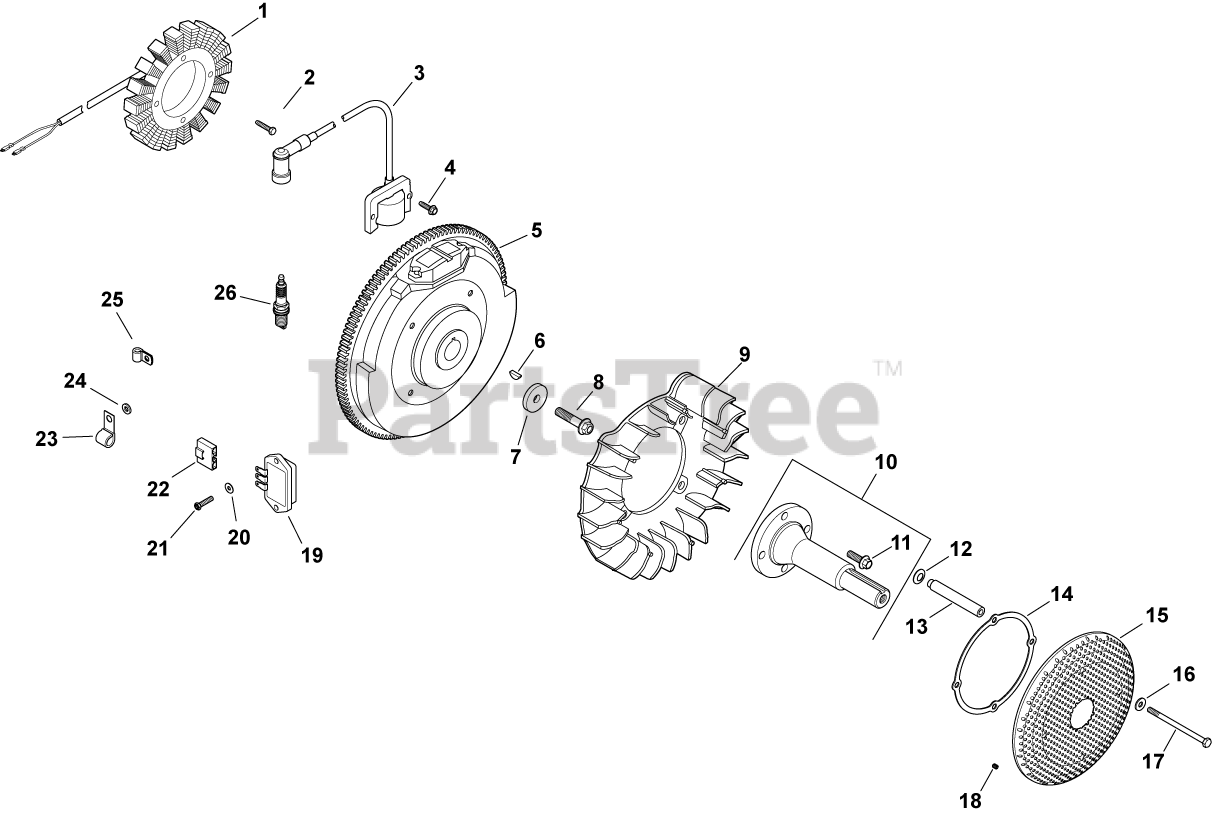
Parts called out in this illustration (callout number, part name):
1	KIT, 15 / 20 AMP STATOR
2	SCREW, M5X0.8X25 - (#25086402S)
3	KIT, MODULE IGNTN (CDI FIXED)
4	SCREW, FLG THD FRM M5X.8X20-(#25086399S)
6	KEY, 3/16" X 5/8"
7	WASHER, FLAT 13/32"
8	SCREW, FLG M10X1.5X45 - (#25086361S)
9	FAN USE 24 755 253-S
10	SHAFT, FRONT DRIVE
11	SCREW, FLG M8X1.25X25
12	WASHER, SPRING 10 MM
14	RING, SUPPORT USE 25 141 08-S
15	SCREEN, GRASS
16	WASHER, FLAT 1/4" (O.D. 5/8")
17	SCREW, CAP M6X1.0X99.5
18	SCREW, SKT SET #10-24X1/4"
19	REG/RECT-15 AMP (KM)-USE 41 403 10-S
20	WASHER, FLAT 7/32"
21	SCREW, PHL HD #11-16X7/8"
22	CONNECTOR (1 CONTACT)
23	CLIP, CABLE
24	WASHER, FLAT 1/4" (O.D. 1/2")
25	CLIP, TUBE & WIRING (KM)
26	PLUG, SPARK (STD)
2417649-S	HARNESS, WIRING
2545403-S	TIE, WIRE
